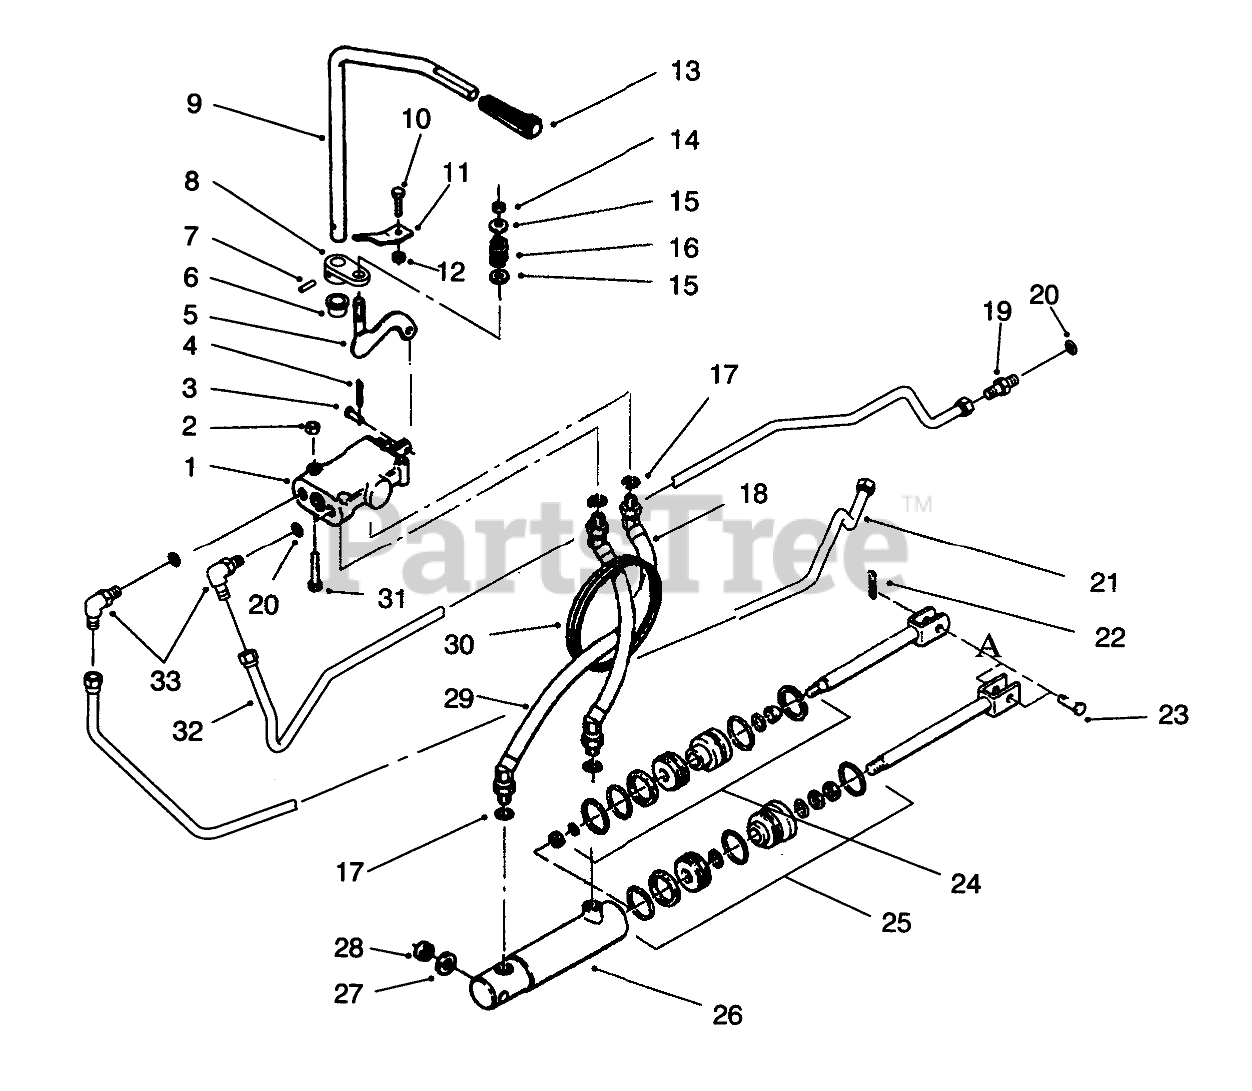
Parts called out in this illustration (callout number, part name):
1	Valve-Hydraulic (Incl. Ref.#3-4)
2	NUT-LOCK, NI
3	PIN-CLEVIS
4	PIN-COTTER
5	WLDMT-LIFT BAR
6	NYLINER BUSHING
7	SPIROL PIN 7/32X7/8
8	ARM-CONTROL
9	ROD-LIFT CONTROL
10	SCREW-HH
11	BRACKET-CONTROL R B
12	NUT-LOCK, NI
13	KNOB-HYDRAULIC LIFT
14	NUT-LOCK, NI
15	WASHER-PLAIN
16	SPRING
17	O RING
18	Hose ASM-Hydraulic
19	Fitting-Straight Adapter (Incl. Ref. #20)
20	0-Ring
21	TUBE-HYD PRESSURE
22	PIN-COTTER
23	Pin-Clevis
24	S/A O-RING&GASKET AS
25	S/A 108872 HYD CYL
26	Cylinder-Hydraulic (Incl. Ref.#24-25)
27	Washer
28	SPACER-OUTER
29	Hose ASM-Hydraulic
30	GROMMET
31	SCREW-HH
32	TUBE-HYDRAULIC
33	Fitting-90deg. (Incl. Ref. #20)
